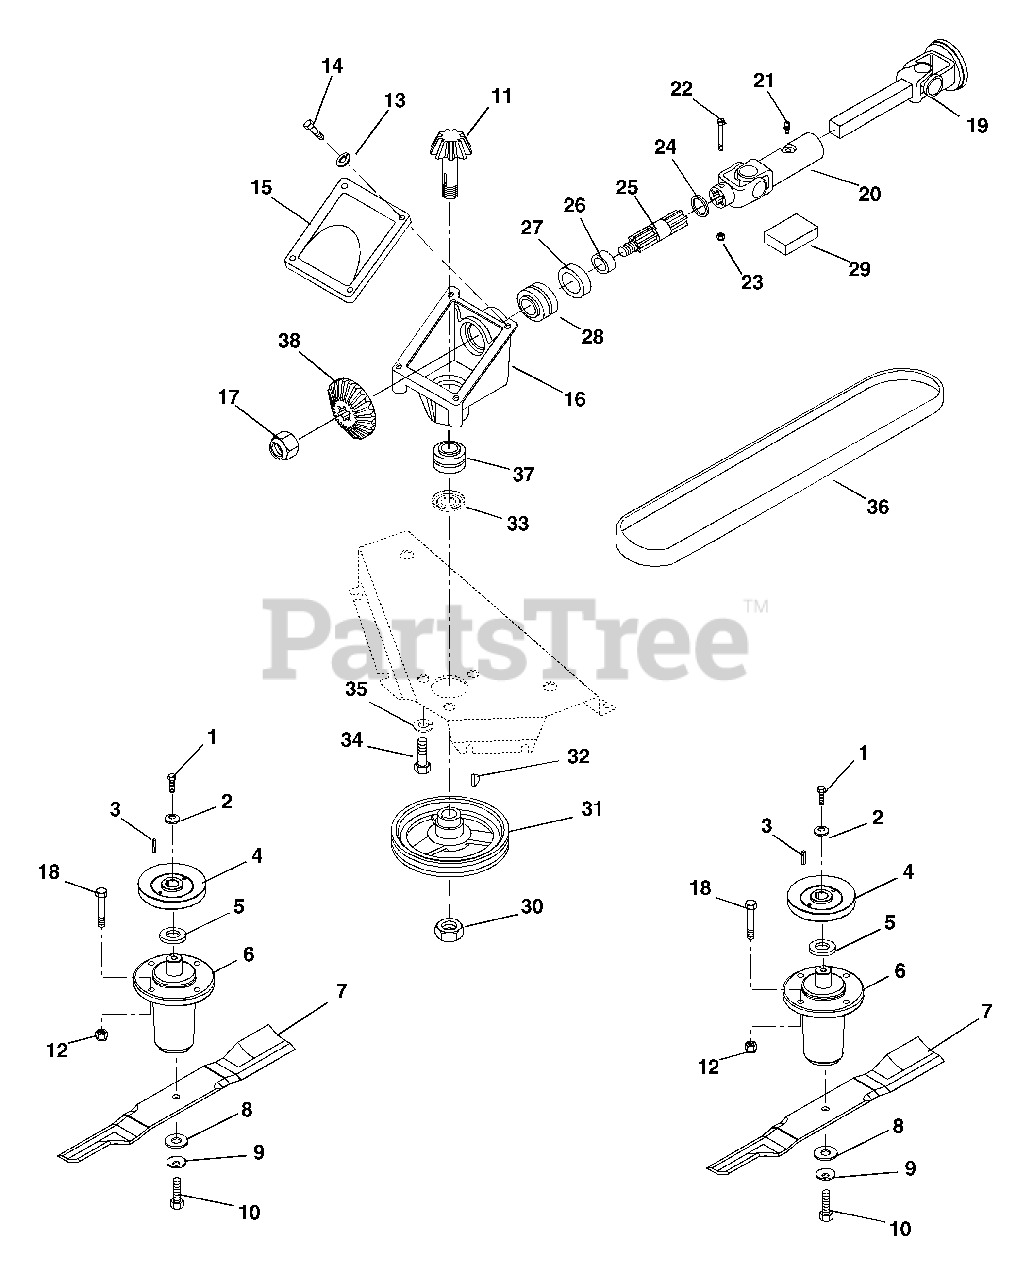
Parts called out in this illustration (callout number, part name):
1	Bolt-Hex .38-16 x 1.00 YZ Grade 8 with Epoxy Patch
2	Washer, Cupped, Serrated .375
3	Key-Square .25X1.00 x .25 SAE 860 OR SAE 1035
4	Sheave, Spindle
5	Slinger, Dust
6	Maintenance Free Spindle Assembly
7	Mower Blade Tungsten Carbide
8	Washer,Flat .64 x 1.81 x .250
9	Washer-Bellville .63 x X1.63 x .14
10	Bolt, Blade
11	Shaft, Gear Pinion
12	Nut-Locking-Nylon .375-16 Grade 2
13	Washer-Locking .25 x .062 Regular
14	Bolt-Hex .25-20 x .50 Grade 5
15	Cover, Gear Housing
16	Casting, Gear Box
17	Nut-Locking-Nylon .75-10
18	Bolt-Hex .38-16 x 1.25 Grade 5
19	Shaft, Prop Square Bar
20	Joint, U Female Eng
21	Fitting, Lube .25-28
22	Bolt-Hex .25-20 x 2.00 Grade 5
23	Nut-Locking-Nylon .25-20
24	Ring-Retaining 1.106 x .95
25	Shaft
26	Bushing Flange 1.00 x 1.25 x 1.25
27	Seal 1.250 x 1.983 x .250
28	Bearing-Assembly 1.000 x 1.980 x 1.243
29	Journal Cross and Bearing Assembly
30	Nut-Jam .75-10
31	Sheave, Drive
32	Key-Woodruff .19 x .63
33	Seal 1.250 x 1.691 x .310
34	Bolt-Hex .50-13 x 1 Grade 5
35	Washer-Locking .50 x .125 Regular
36	V-Belt A-Section 33.25 x .504
37	Bearing-Assembly .75 x 1.781 x 1.499
38	Gear, Bevel
